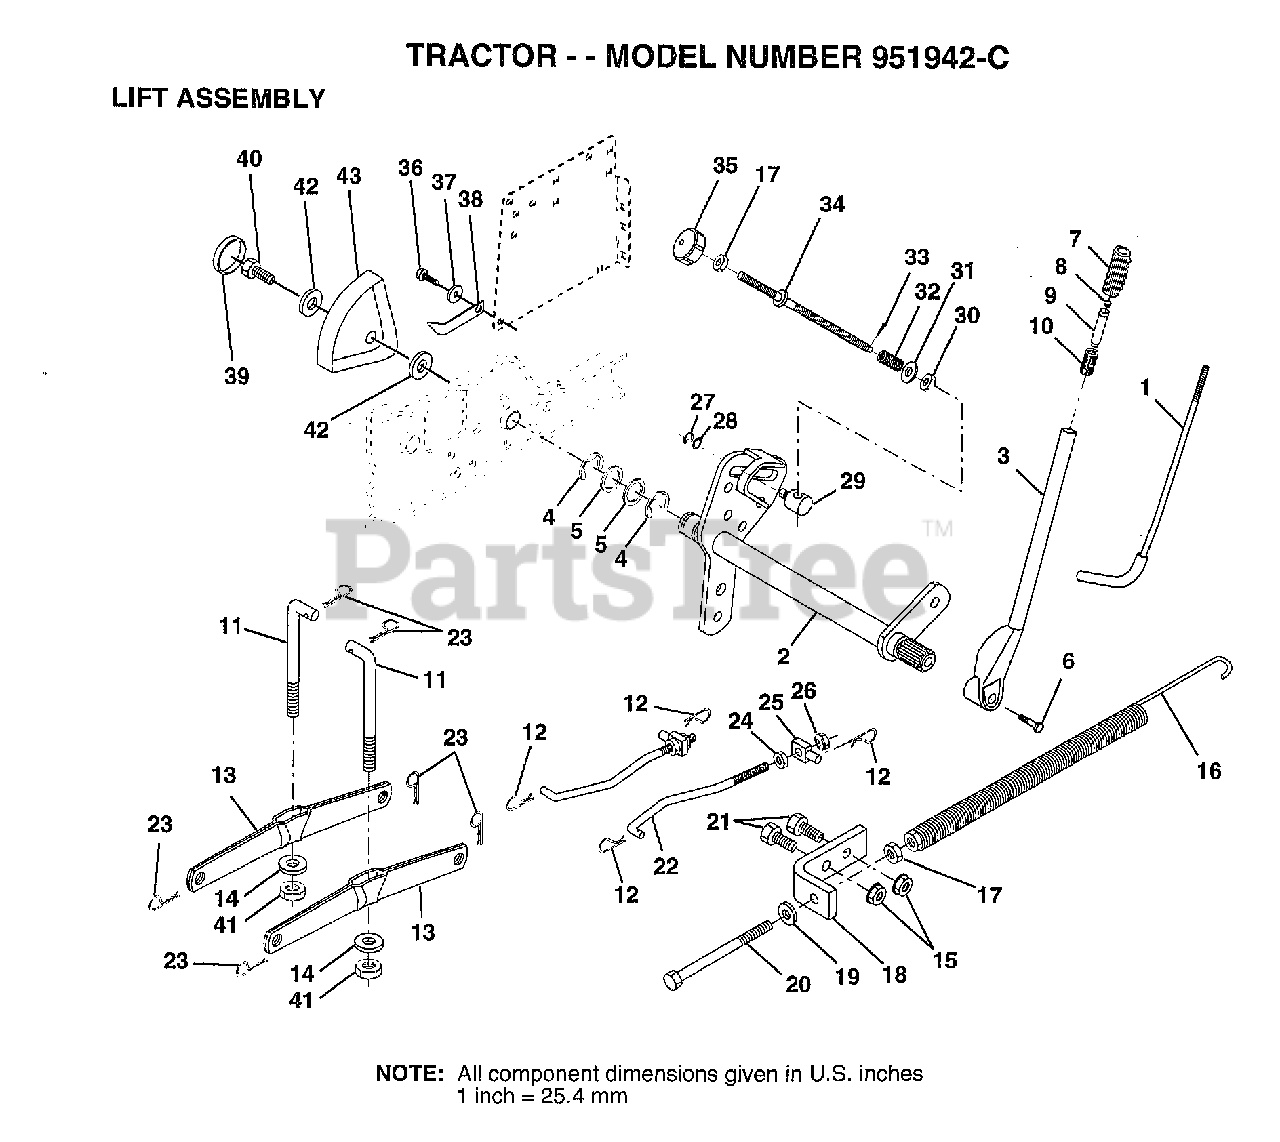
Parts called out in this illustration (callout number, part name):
1	LEVER ROD LT
2	SHAFT.LIFT.VGT.95
4	E-RING
5	WASHER
6	"BOLT,HEX"
7	GRIP HANDLE
10	SPRING T
11	LINK.LIFT.MWR.VGT
12	RETAINER.SPRING
13	ARM SUSP REAR
14	BEARING PVT LH
17	NUT
18	BRACKET SPRING AS
19	WASHER
20	BOLT-ADJ SPRING T
21	BOLT
22	LINK.FRONT
24	NUT
25	TRUNION
26	NUT.LK.W/WSH.1/2.
27	KLIP RING
28	WASHER
29	TRUNION LT
30	NUT T
31	WASHER
32	SPRING.COMP.INF.H
34	ROD.ADJ.LIFT
35	KNOB INF 3/8-16
36	SCREW
37	WASHER T
38	POINTER HGT IND
39	"PLUG,HOLE"
40	SCREW
41	NUT.CROWNLOCK.3/8
42	WASHER
43	HEIGHT INDICATOR
